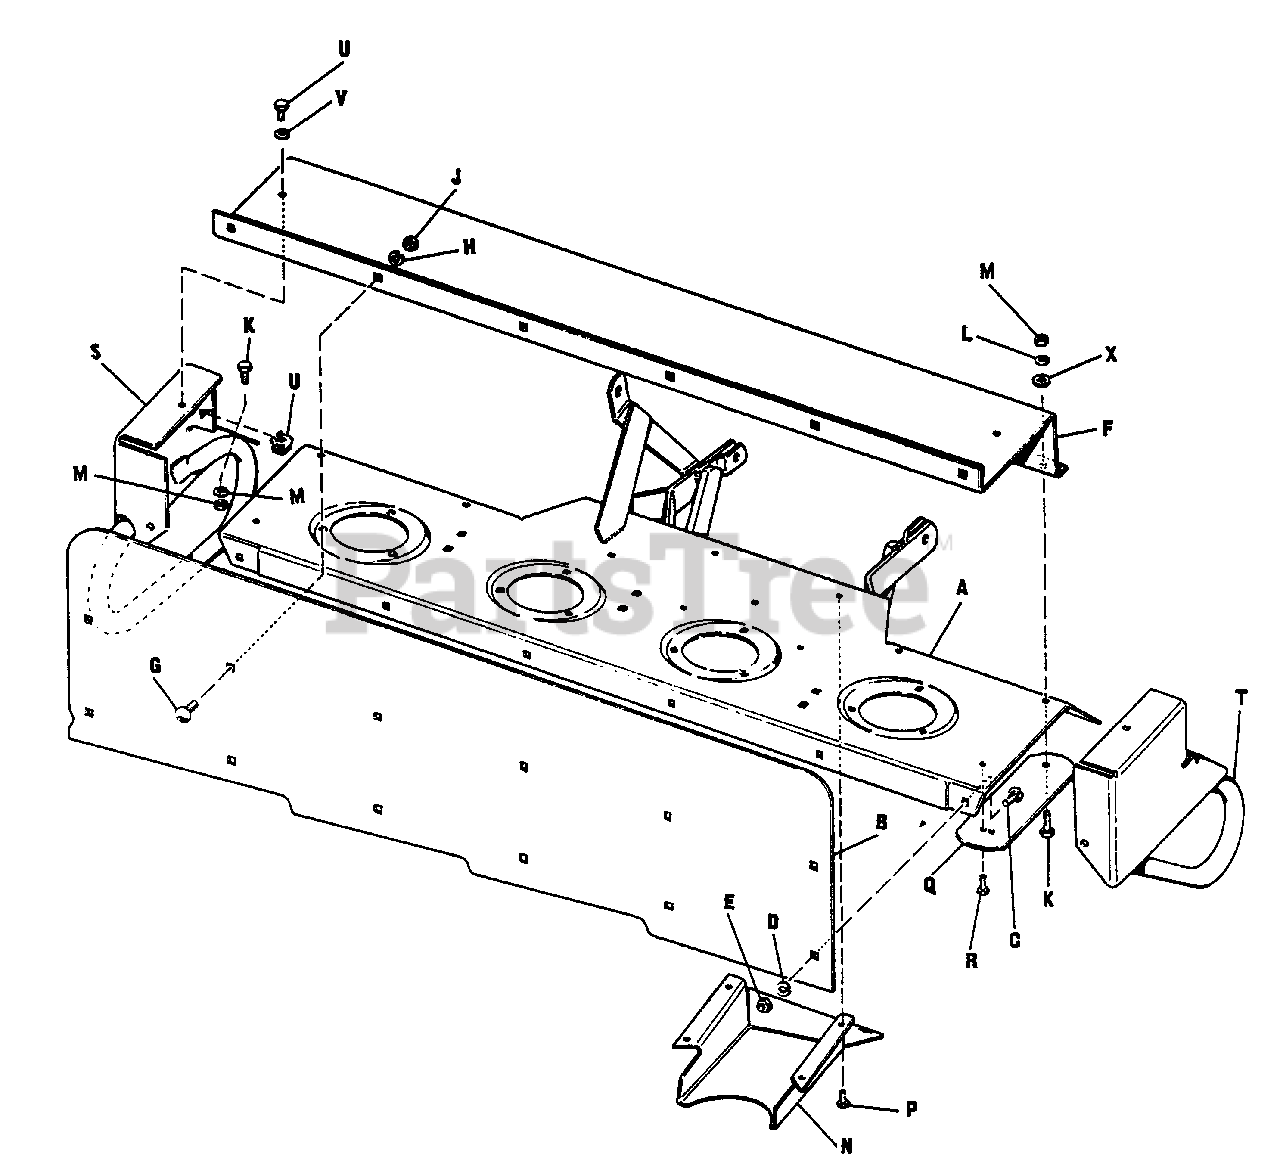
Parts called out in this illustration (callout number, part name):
A	Housing Assembly
B	Front Plate
C	Carriage. Bolt, 5/16"-18 x 3/4"
D	Lock Washer, 5/16"
E	Full Hex Nut, 5/16"-18
F	Spindle Cover
G	Carriage Bolt, 5/16"-18 x 3/4"
H	Lock Washer, 5/16"
J	Full Hex. Nut, 5/16"-18
K	Hex Cap Screw, 5/16" -18 x 3/4"
L	Lock Washer, 5/16"
M	Full Hex Nut, 5/16"-18
N	Belt Cover
P	Std. Screw Taptite, 1/4"-20 x 3/8
R	Std. Screw Taptite, 1/4"-20 x 3/8"
S	R.H. End Cap Assembly
T	L.H. End Cap Assembly
U	Tinnerman Nut, 5/16"-18
V	Hex Cap Screw, 5/16"-18 x 5/8"
W	Lock Washer, 5/16"
X	Plain Washer, 5/16"
